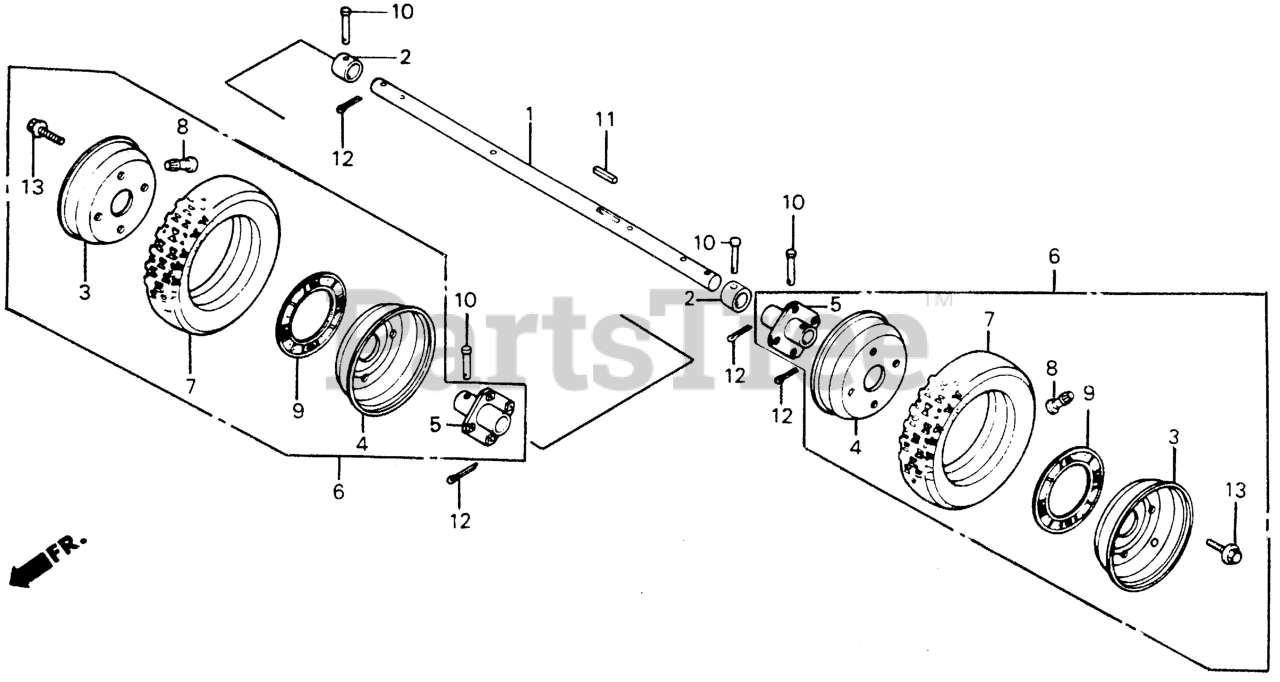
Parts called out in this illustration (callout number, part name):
1	SHAFT, WHEEL
2	COLLAR, WHEEL SHAFT
3	WHEEL A (3SPWX6DCT)
4	WHEEL B (3SPWX6DCT)
5	HUB, TIRE (HA-TYPE) (NOT AVAILABLE)
6	TIRE ASSY. (14X4.0-6 B-905)
7	TIRE (14X4.00-6)
8	VALVE, RIM (SCHRADER)
8	VALVE, RIM (TAIHEIYO)
9	GASKET (U-75)
10	PIN (6.2X38)
11	KEY (5X5X21)
12	PIN, COTTER (3.0X18)
13	BOLT, FLANGE (8X16) Use from Engine SN 1000016.
